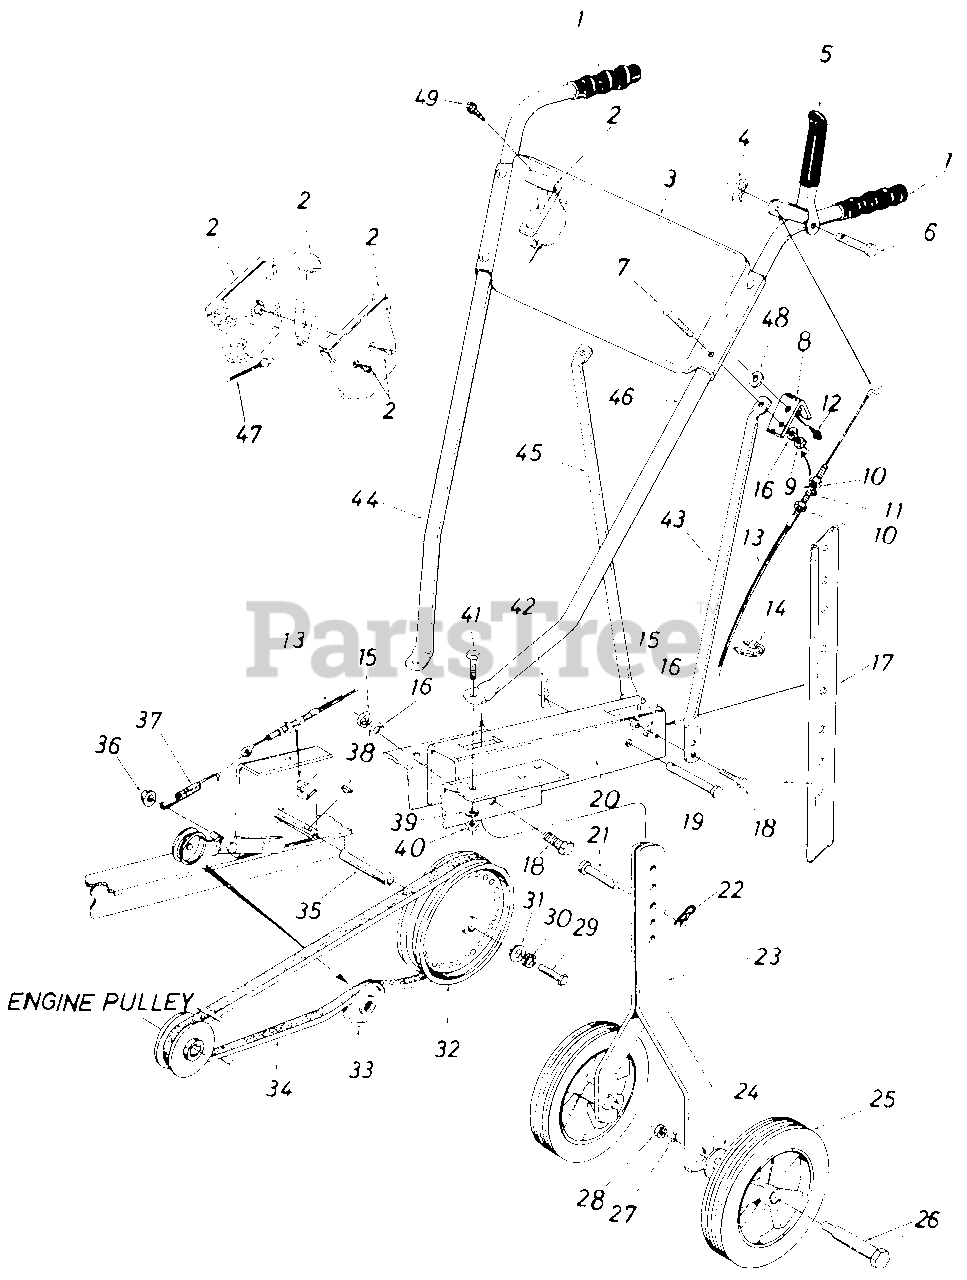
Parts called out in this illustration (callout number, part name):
2	Throttle Control Box
3	Handle Panel
4	Int. Cotter Pin
5	Clutch Grip Ass'y.
7	Carriage Bolt 5/16-18 x 1.75" Lg.*
8	Cable Support Brkt.
9	Hex Nut 5/16-18 Thd.*
10	Hex Jam Nut 5/16-24 Thd.
11	L-Wash. 5/16" I.D.
12	Hex Wash. Hd. Self-Tap Scr. 1/4-20 x .50" Lg.
13	Clutch Control Cable
15	Hex Nut 5/16-18 Thd.*
16	L-Wash. 5/16" I.D.*
18	Hex Bolt 5/16-18 x .75" Lg.*
19	Clevis Pin 1/2" Dia. x 2.50" Lg.
20	Tailpiece Ass'y.
21	Clevis Pin 3/8" Dia. x 2.50" Lg.
22	Hairpin Cotter
23	Wheel Bracket Ass'y.
24	Belleville Wash. 1/2" I.D.
25	Wheel Ass'y. 9 x 1.75
26	Shoulder Bolt
27	L-Wash. 1/2" I.D.*
28	Hex Nut 1/2-20 Thd.*
29	Hex Bolt 1/4-28 x .75" Lg.
30	L-Wash. 1/4" I.D.'
31	Fl-Wash. .25" I.D. x .930" O.D.
32	Pulley 6.00" O.D.
33	Idler Pulley
34	"V"-Belt 1/2" Pitch x 39" Lg.
36	Cap Speed Nut
37	Extension Spring
38	Hi-Pro Key
39	L-Wash. 5/16" I.D.*
40	Hex Nut 5/16-18 Thd.*
41	Hex Bolt 5/16-18 x .75" Lg.
42	Hairpin Cotter
43	Handle Support Bracket* L.H.
44	Handle Bar-R.H.
45	Handle Support Bracket-R.H.
46	Handle Bar-L.H.
47	Throttle Control Cable-35"
48	Fl-Wash. .281" I.D. x .50" O.D.
49	Self-Tap Scr. #10 x 1/2" Lg.
